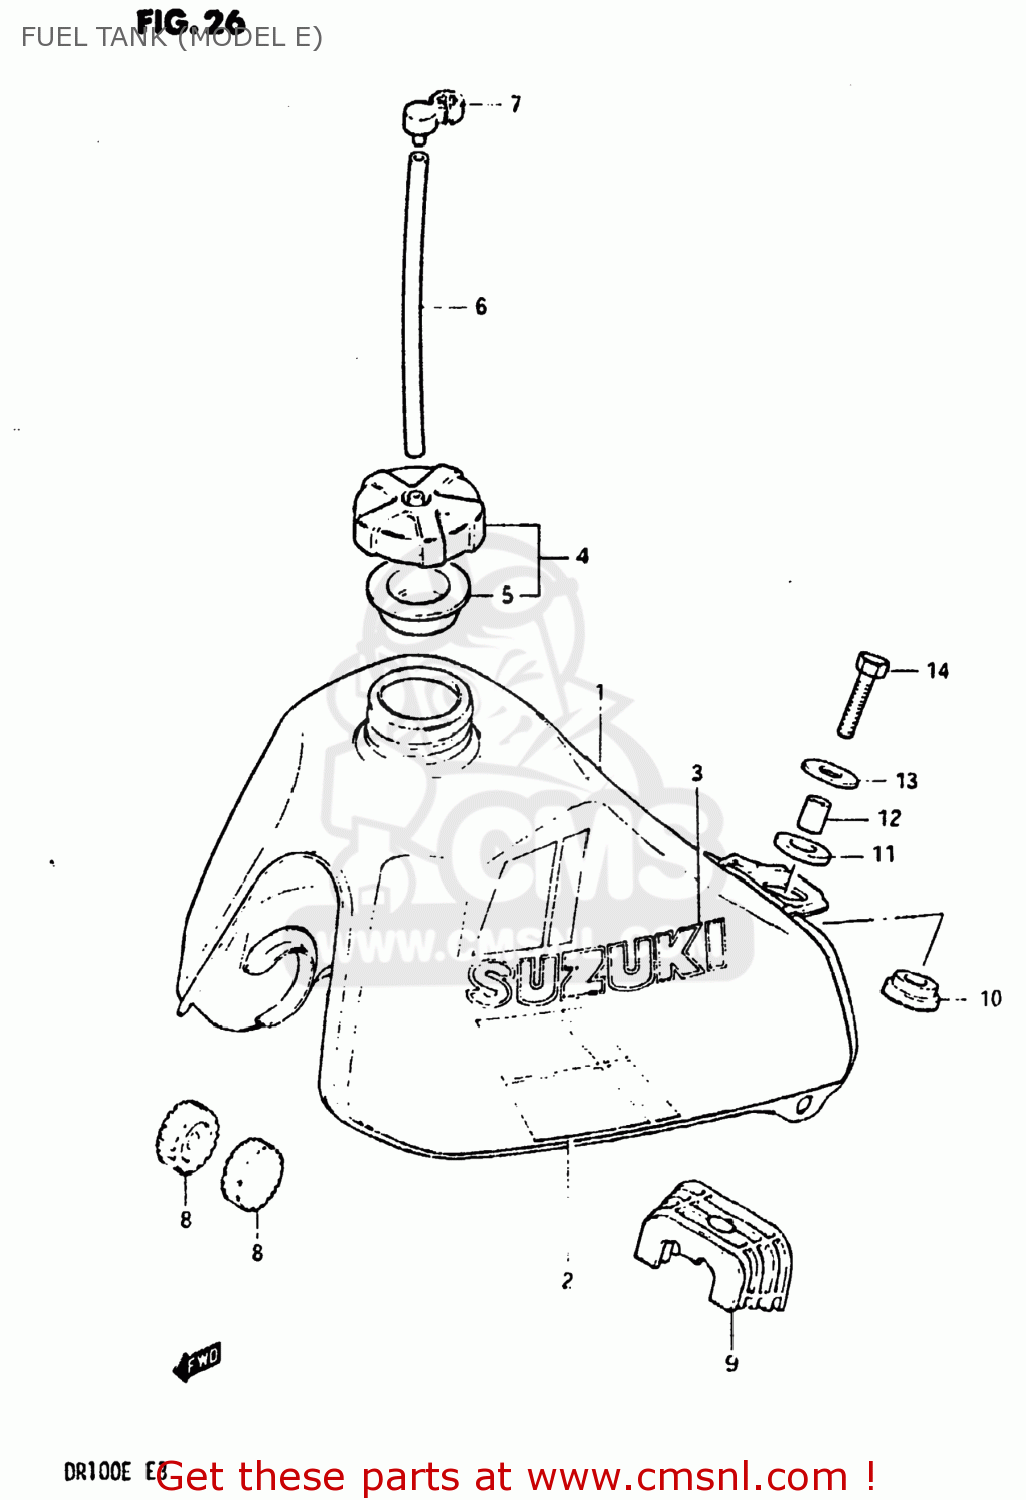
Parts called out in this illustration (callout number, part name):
1	TANK ASSEMBLY,FUEL
2	TAPE SET,FUEL TANK
3	EMBLEM(BLACK)
4	CAP SET,FUEL TANK
5	GASKET (NAS)
6	HOSE
7	CLAMP,FUEL TANK BREATHER HOSE
8	CUSHION
9	CUSHION,FUEL TANK
10	CUSHION
11	CUSHION
12	SPACER(8.5X12X19)
13	WASHER (8.5X29X1.6)
14	BOLT (8X30)
